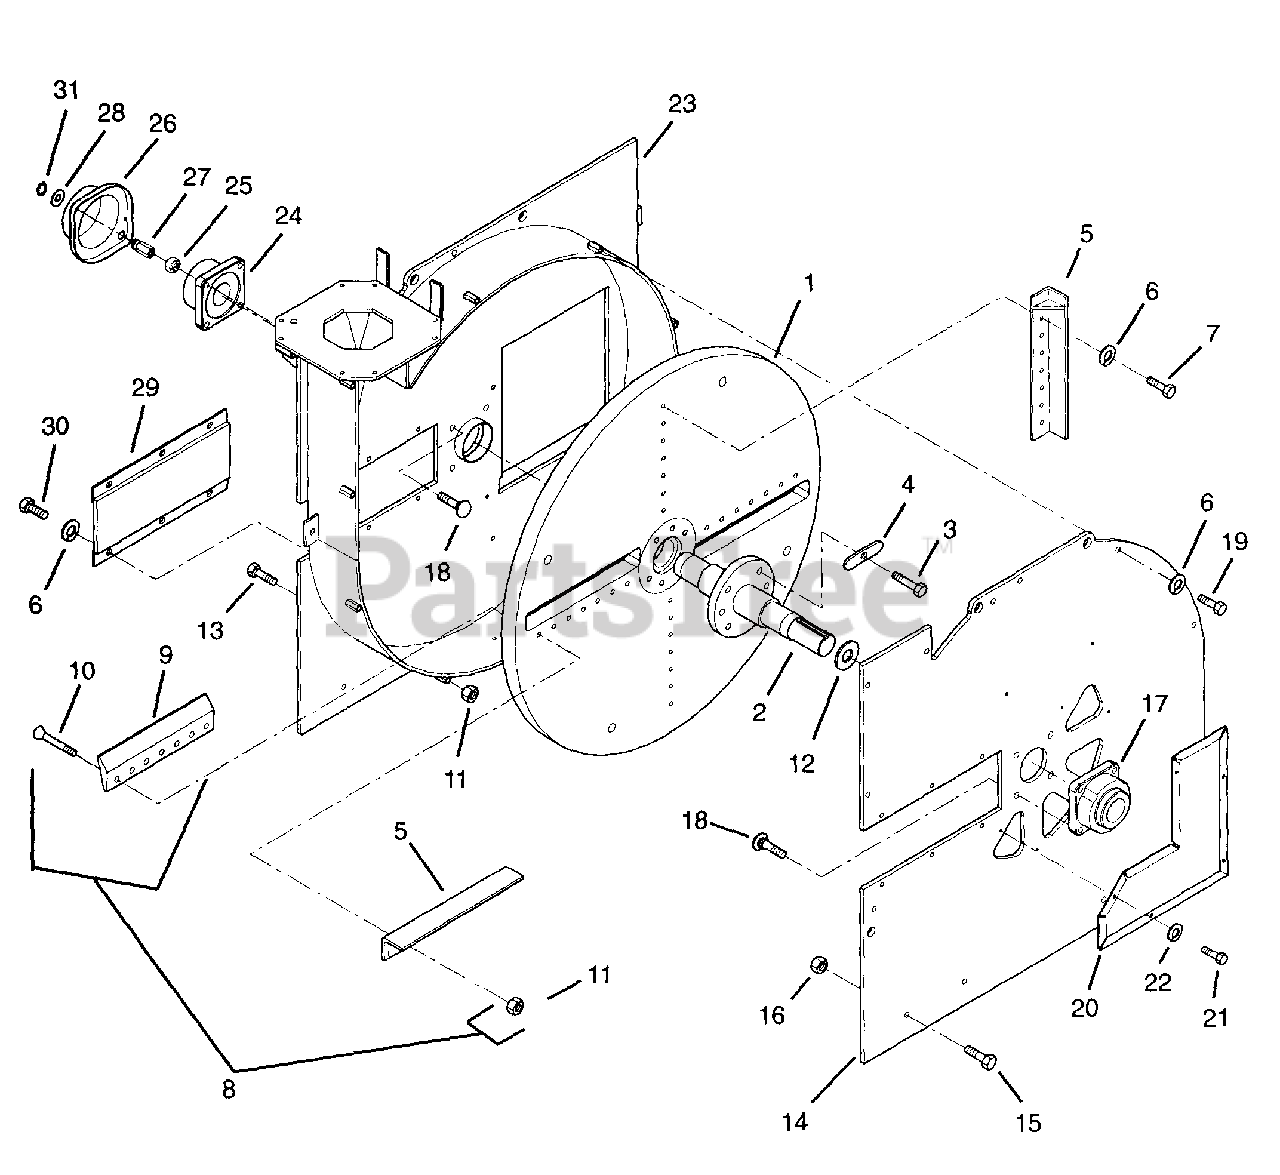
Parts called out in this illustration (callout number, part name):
1	Flywheel
2	Flywheel Shaft Weldment
3	Bolt-Hex .62-11 x 2.25 Grade 8
4	Lock Tab
5	Impeller Weldment
6	Washer-Lock .50 x .125
7	Bolt-Hex .50-13 x 1.25 Grade 5
8	Chipper Knife Set 495
10	Screw-Socket Head .50-33 x 3.5 Grade 8
11	Nut-Locking .50-13
12	Arbor Shim
13	Bolt-Hex .50-13 x 1.25
14	Housing (Front)
15	Bolt-Hex .75-10 x 1.50 Grade 5
16	Nut-Locking-Center .75-10
17	Bearing-Flange 2.00
18	Rib Neck Bolt
19	Bolt-Hex .50-13 x 1.75 Grade 8
20	Screen Frame Weldment
21	Bolt-Hex .31-18 x 1.75 Grade 5
22	Washer-Lock .313 x .078
23	Housing (Rear)
24	Bearing-Flange 2.00 Inside Diameter-Non-Expandable
25	Nut-Locking Flex
26	Bearing Cover
28	Washer-Flat-Steel .754 X 1.125 X .062
29	Access Cover Weldment
30	Bolt-Hex .50-13 x 1.00 Grade 5
31	Ring-Retaining-External .750 x .042
